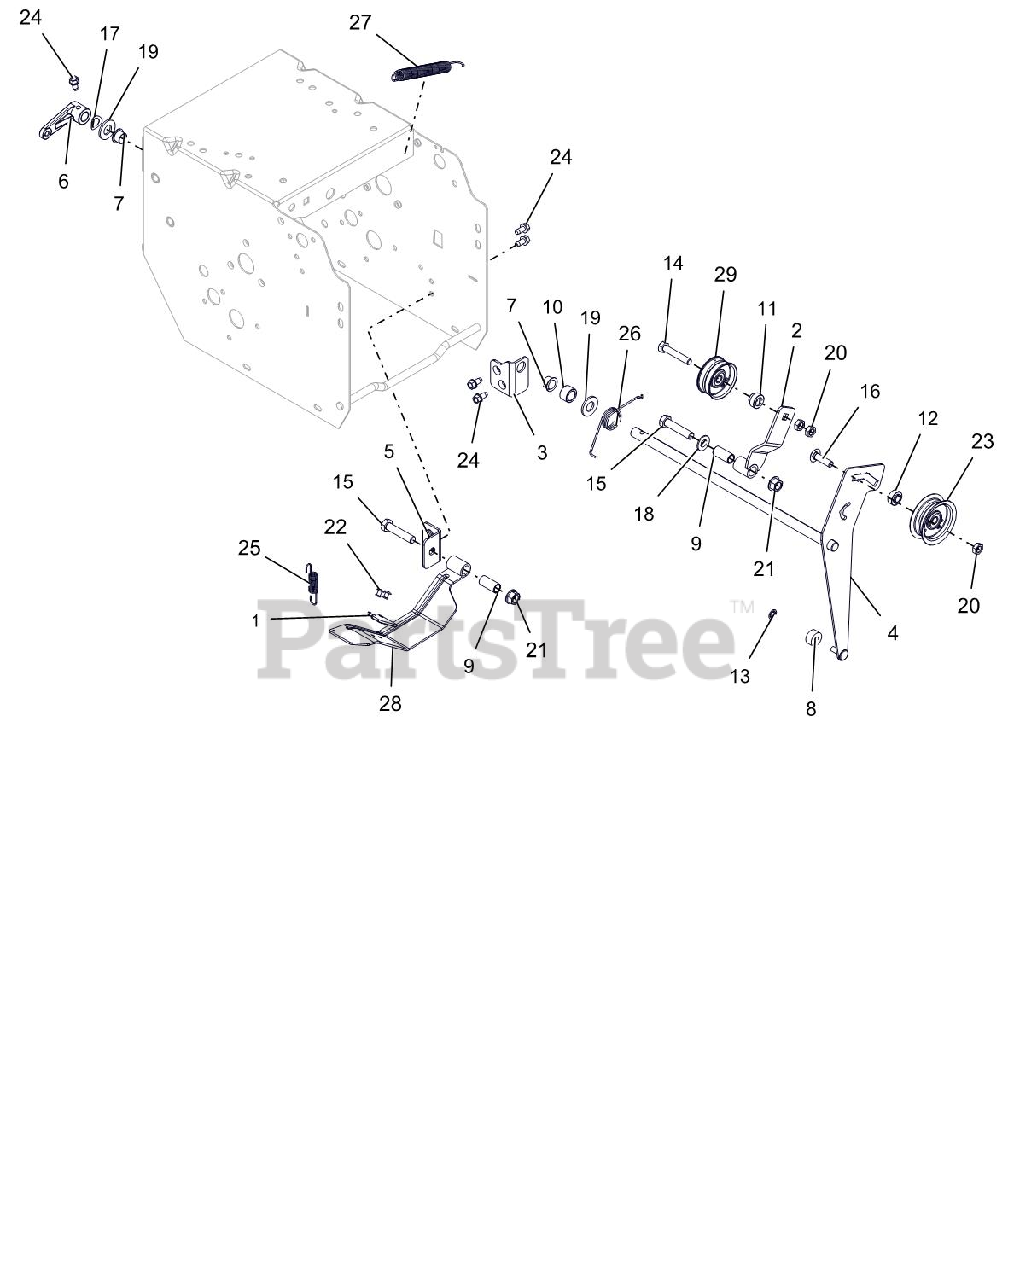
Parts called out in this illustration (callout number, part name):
1	PAD, BRAKE
2	ARM, TRACTION IDLER
3	BRACKET, MOUNT - IDLER ARM
4	WELDMENT, ATTACHMENT IDLER ARM
5	BRACKET, MOUNT - BRAKE
6	ARM, CLUTCH - ATTACHMENT
7	BUSHING, POLYLINER-.50 SPLIT
8	BSHG,SLV .265 X .625 X .375
9	BSHG-SLV .385X.500X1.045
10	BSHG-SLV .510X.751X.475
11	SPCR, BRG .315X.500X.481X.281
12	SPCR, BRG .315X.500X.358X.281
13	RG-RTNG-EXT .250X.010
14	@BLT-HEX .31-18X1.75 GR5 YWZC
15	@BLT-HEX .38-16X1.75 GR5 YWZC
16	BLT-RDHDSQSHNK.31-18X1.13 G5YZ
17	WSHR-WAVE .50X.75X.015 .13FRHT
18	@WSHR-FL-STL.406X.812X.065 YWZ
19	@WSHR-FL-STL.531X1.06X.095YWZC
20	@NUT-LK-CTR-JAM .31-18 YWZC
21	@NUT-LK-TOP-FLG .38-16 YWZC
22	RVT-POP .187 YZ
23	IDLER, FLAT - 2.00"
24	SCR-TAP .25-20X.50 HWH TR YWZ
25	SPRING-EXT .437 X .438 X 2.64
26	SG-TORS .075 X .955
27	SPRING, EXTENSION
28	BRAKE ARM W/PAD
29	IDLER, FLAT - 1.875"
